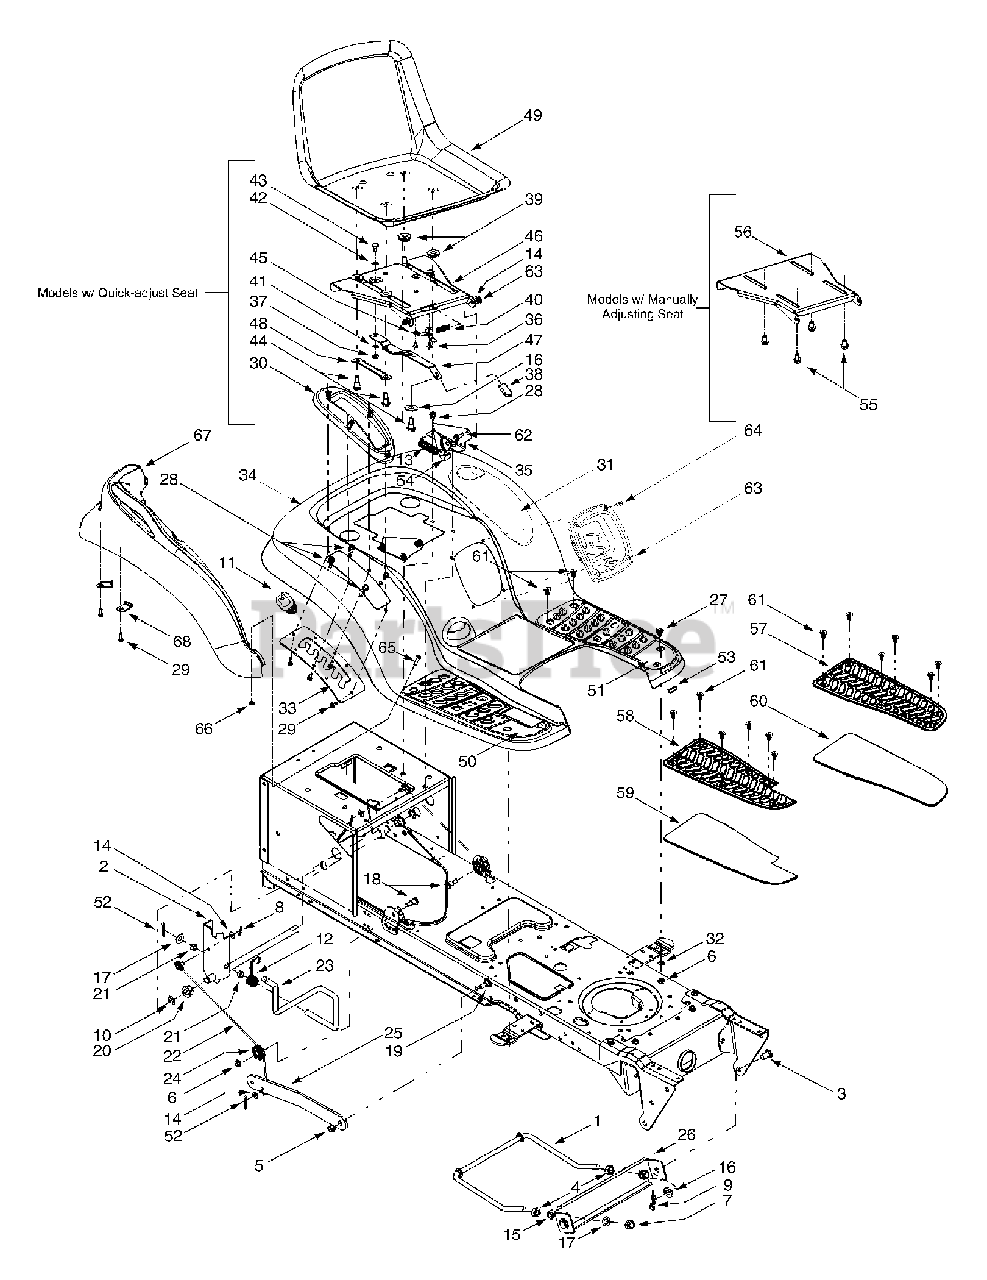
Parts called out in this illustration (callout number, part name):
1	Deck Stabilizer Rod
4	Hex Nut, 1/2-13
5	Flange Lock Nut, 3/8-16
6	Flange Lock Nut, 5/16-18
7	Hex Nut, 1/2-13
8	Internal Cotter Pin
9	Internal Cotter Pin
10	E-ring
11	Handle Grip
12	Torsion Spring
13	Extension Spring, .84 x 4.6
14	Flat Washer, 5/16
15	Lock Washer, 1/2
16	Flat Washer, .31 x 1.062 x .134
17	Flat Washer, .51 x 1.12 x .06
18	Hex Cap Screw, 5/16-18 x .62
19	Shoulder Screw, 3/8-16
20	Hex Flange Bearing
21	Snap Flange Bearing
22	Lift Cable, 16.16
23	Lift Handle
24	Roller Pulley
27	Carriage Bolt, 5/16 x .62
28	Self-tapping Screw, 5/16-18 x .625
29	Self-tapping Screw, 1/4-15 x .75
30	Lift Lever Cover
31	Cover w/ Cup Holder
32	Flat Washer, .349 x 1.0 x .063
36	Screw, #10-16 x .375
37	Hex Flange Lock Nut, 1/4-20
38	Seat Adjuster Grip
39	Spacer
40	Compression Spring, .41 x 1.5
41	Spring Washer, .265 x .562 x .025
42	Flat Washer, .344 x .62 x .03
43	Shoulder Screw, .340 x .285,1/4-20
44	Shoulder Screw, .50 x .50, 3/8-16
45	Seat Stop
48	Seat Adjustment Selector
49	High Back Seat, Black
50	RH Foot Pad, Rubber (4-Style Fender)
51	LH Foot Pad, Rubber (4-Style Fender)
52	Cotter Pin
53	Trim Strip
54	Seat Lift Bracket
55	Hex Head Washer Screw, 3/8-16 x .625
58	LH Foot Pad, Rubber (7-Style Fender)
59	RH Foot Pad, Grit (7-Style Fender)
60	LH Foot Pad, Grit (7-Style Fender)
61	Ratchet Clip
62	Shoulder Screw, .437 x .286
63	Shift Cover
64	Self-tapping Screw, 1/4-20 x .75
65	Screw, 1/4-20 x 1.0
66	Hex Sems Nut, 1/4-20
67	RH Fender Flare
68	Fender Clips
